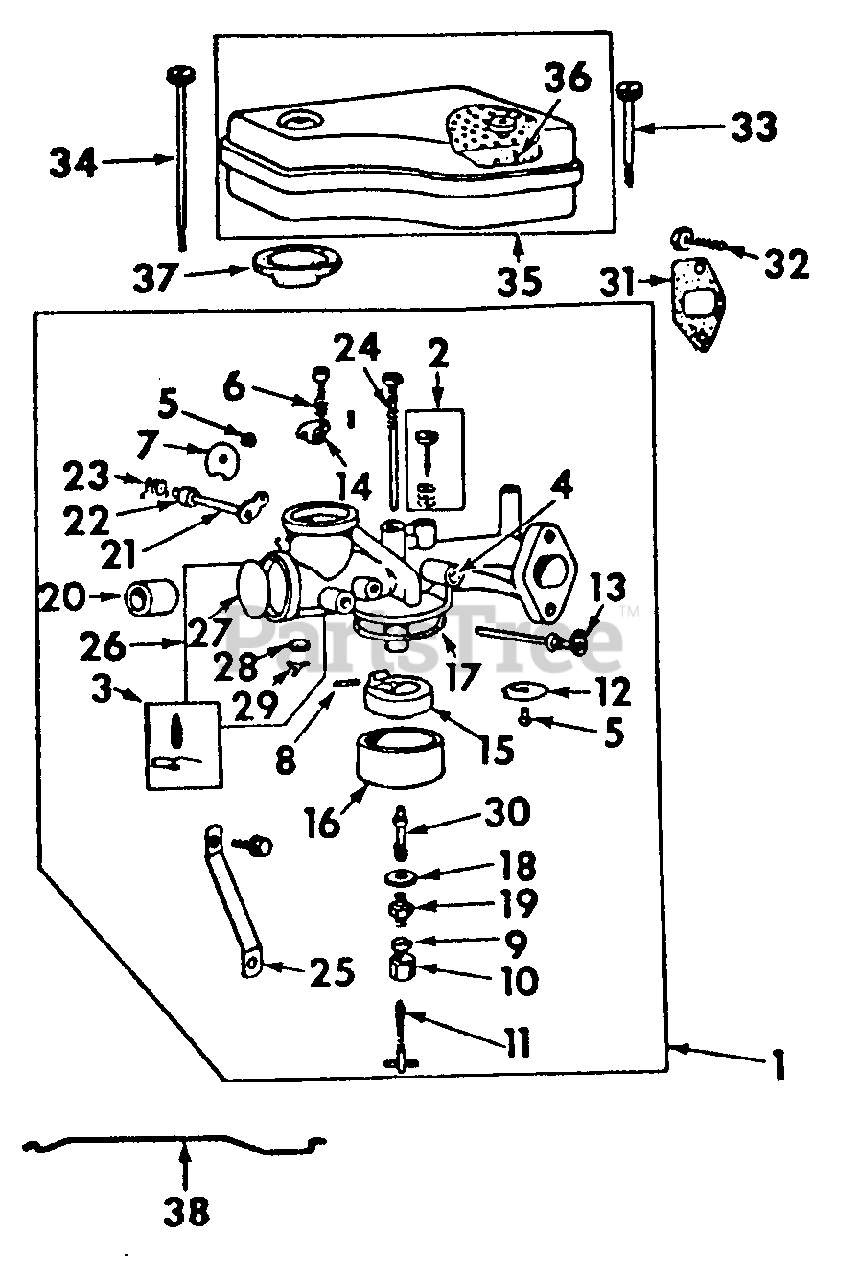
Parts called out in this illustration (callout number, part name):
1	Carburetor Assy
2	Valve Assy, Idle
3	Valve Assy, Float
4	Bushing, Throttle Shaft
5	Screw, Choke Valve
6	Spring, Throttle Adj
7	Valve, Choke
8	Pin, Float
9	Packing, Needle Jet
10	Nut, Needle Jet Packing
11	Valve, Needle
12	Valve, Throttle
13	Shaft & Lever Assy Throttle
14	Stop, Throttle
15	Float
16	Bowl, Float
17	Gasket, Bowl
18	Washer, Float Bowl
19	Retainer, Needle Jet
20	Venturi
21	Shaft & Lever Assy Choke
22	Washer, Choke Shaft Felt
23	Spring, Choke Return
24	Jet, Idle Needle
25	Bracket
26	Body Assy
27	Plug, Expansion
28	Filter, Drain
29	Retainer
30	Screw, Jet
31	Gasket, Carburetor
32	Screw, Carburetor Mtg
33	Screw, Air Cleaner
34	Screw, Air Cleaner
35	Cleaner Assy, Air
36	Element
37	Gasket, Air Cleaner
38	Link, Choke
